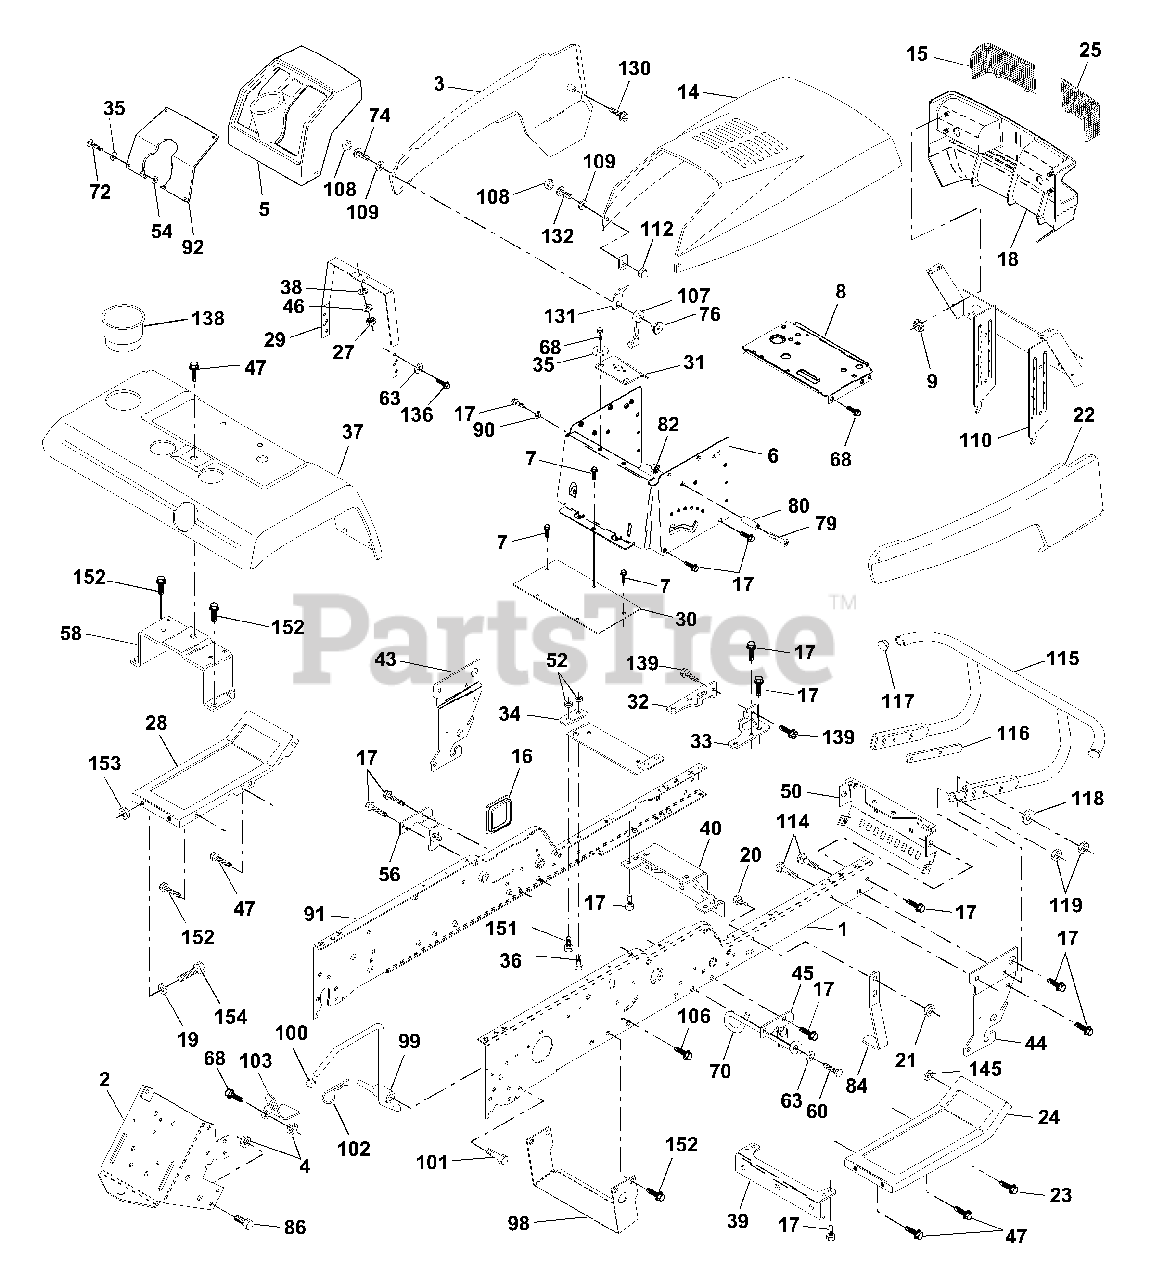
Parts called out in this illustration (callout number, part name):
1	Rail, Frame RH
2	Drawbar, Gt
3	Panel Asm., Side LH
4	Nut, Crownlock 7/16-14 Unc
5	Dash, Plastic Black
6	Dash 1-PCS, Lower
7	Screw, Thd Cut 1/4-20 x 1/2
8	Support, Battery
14	Hood Asm., Pnt
15	Lens, Headlight LH
16	Cover, Access
17	Screw 3/8-16 x 3/4
19	Washer 13/32 x 13/16 x 12 Ga.
20	Bolt, Fin Hex 3/8-16 x 1
21	Nut, Crownlock 3/8-16 Unc
22	Panel Asm., Side RH
23	Screw 3/8-16 x 1/2
24	Footrest, RH
25	Lens Headlight RH
27	Nut Fin Hex 1/4-20
28	Footrest, LH
29	Bracket, Support Dash
31	Brace, Support Steering
32	Bracket Asm., Frame Pivot Lh
33	Bracket Asm., Frame Pivot Rh
34	Bracket, Engine Support Rear
35	Washer 11/32 x 11/16 x 16 Ga.
36	Bolt, Fin Hex 5/16-18 x 3/4
37	Fender, Pnt.
38	Washer, Lock 1/4
39	Bracket, Axle Front
40	Bracket, Support Axle/Engine
43	Bracket, Spnsn Front Lh
44	Bracket, Spnsn Front Rh
45	Bracket Asm., Susp Chassis Rh
46	Washer 9/32 x 3/4 x 16 Ga.
47	Screw Thdrol 3/8-16 x 1/2
50	Bracket, Chassis Front
52	Locknut, Hex W/Ins 5/16-18 Unc
54	Nut 5/16-18
56	Bracket Asm., Susp Chassis Lh
58	Bracket Asm., Fender
60	Screw 3/8-16 x 1-1/4
63	Washer 13/32 x 1 x 14 Ga.
68	Screw, Thdrol 5/16-18 x 1/2
70	Guide, Belt Mid Span
72	Screw, Mach Trhd 5/16-18 x 3/4
74	Screw, Machine #10-24
76	Nut, Weld #10-24
79	Screw, Machine #10-24 x 1/4
80	Spacer, Split
82	Nut #10-24
84	Stop, Over Center 44" 20/23" T. 94
86	Bolt, Fin Hex 7/16-14 Unc x 1
90	Washer, Lock External Tooth 3/8
91	Rail, Frame Lh
92	Plate, Silkscreen Dash
98	Bracket Chassis Skid
99	Rod Asm. Bypass
100	Cap Brake Parking Black
101	Screw Thdrol. 3/8-16 x 1-3/4
102	Retainer Spring 1"
103	Bracket Lock Bypass
106	Screw Thdrol. Hex Hd Zinc Mur
107	Latch, Chute Blk
108	Cap, Snap Black
109	Cap, Washer Snap
110	Pivot Asm. Grille/Hood Husq. VGT
112	Nut, Acorn, Hex #10-24
114	Bolt, Carriage 3/8-16 x 1-1/4
115	Bumper Asm.
116	Bracket Extension Bumper
117	Plug Plastic
118	Washer 13/32 x 13/16 x 16 Ga.
119	Nut Crownlock 3/8-16 UNC
130	Screw HWHD Hi-Lo #13-16 x 3/4
131	Bracket Support Hood/Panel YP
132	Screw Truss Hd. #10-24 x 3/8
136	Screw 3/8-16 x 3/4
138	Cupholder YTGT Grey
139	Bolt, Shoulder 5/16-18 TT
145	Washer Flat 13/32 x 7/8 x 16 Ga.
151	Screw 5/16-18 x 3/4
152	Screw 3/8-16 x 3/4
153	Nut Crownlock 3/8-16 Unc
154	Bolt Hex Fin 3/8-13 x 1
